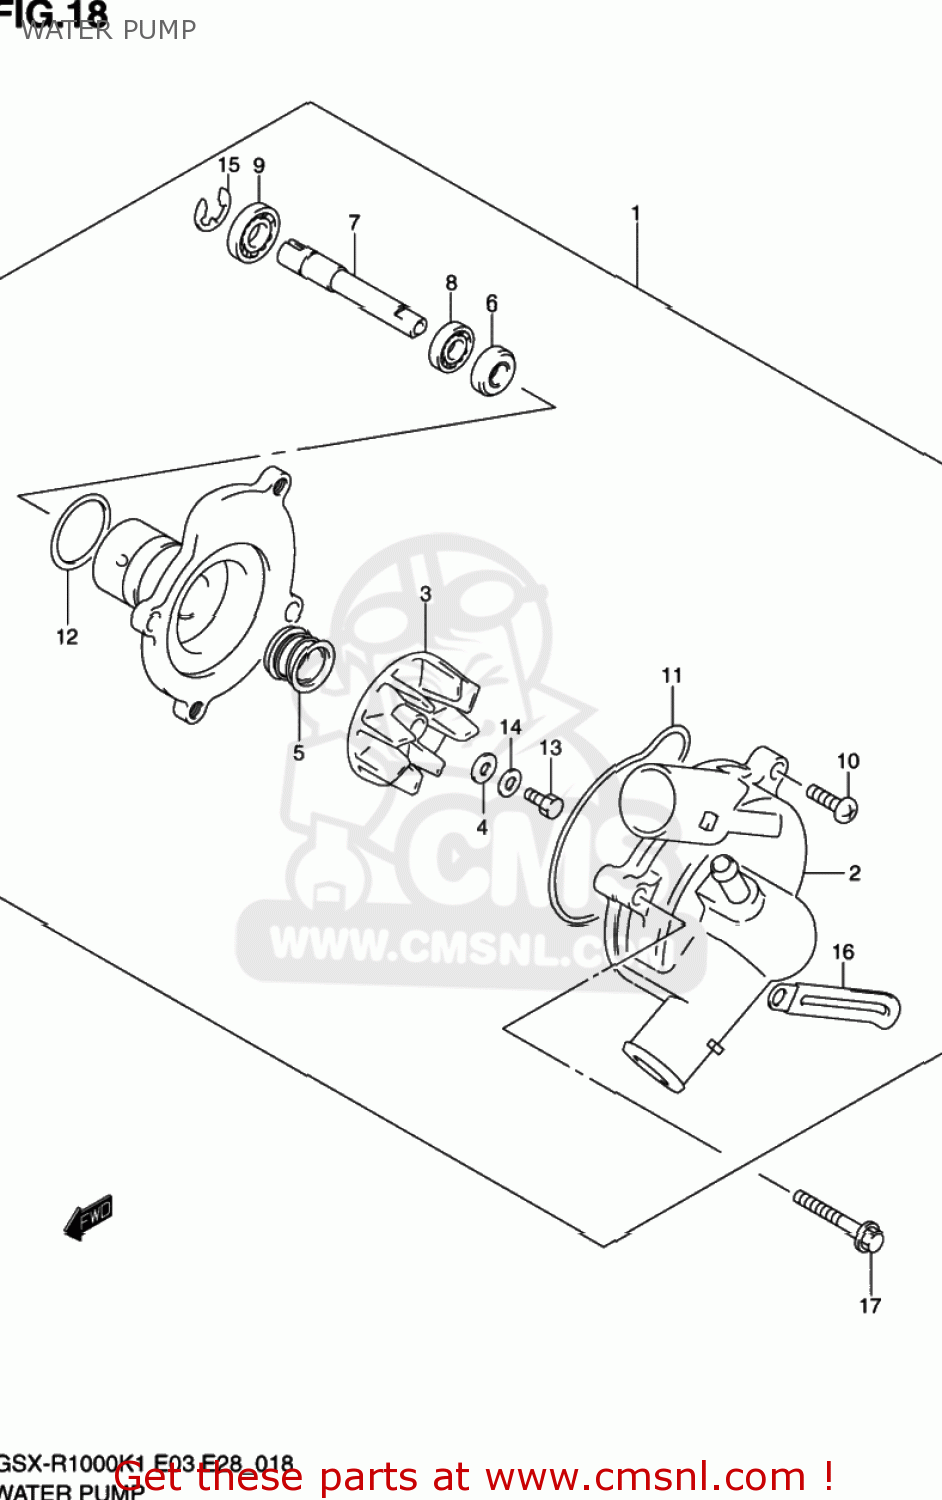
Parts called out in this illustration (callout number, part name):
1	PUMP ASSY,WATER
2	CASE,WATER PUMP
3	IMPELLER
4	GASKET(6X15X2.2) (NAS)
5	SEAL,MECHANICAL
6	SEAL,OIL
7	SHAFT
8	BEARING(10X26X8)
9	BEARING(12X28X8)
10	SCREW 6X16
11	O RING
12	O RING
13	BOLT(6X13)
14	WASHER
15	E RING
16	CLAMP(L:65)
17	BOLT
